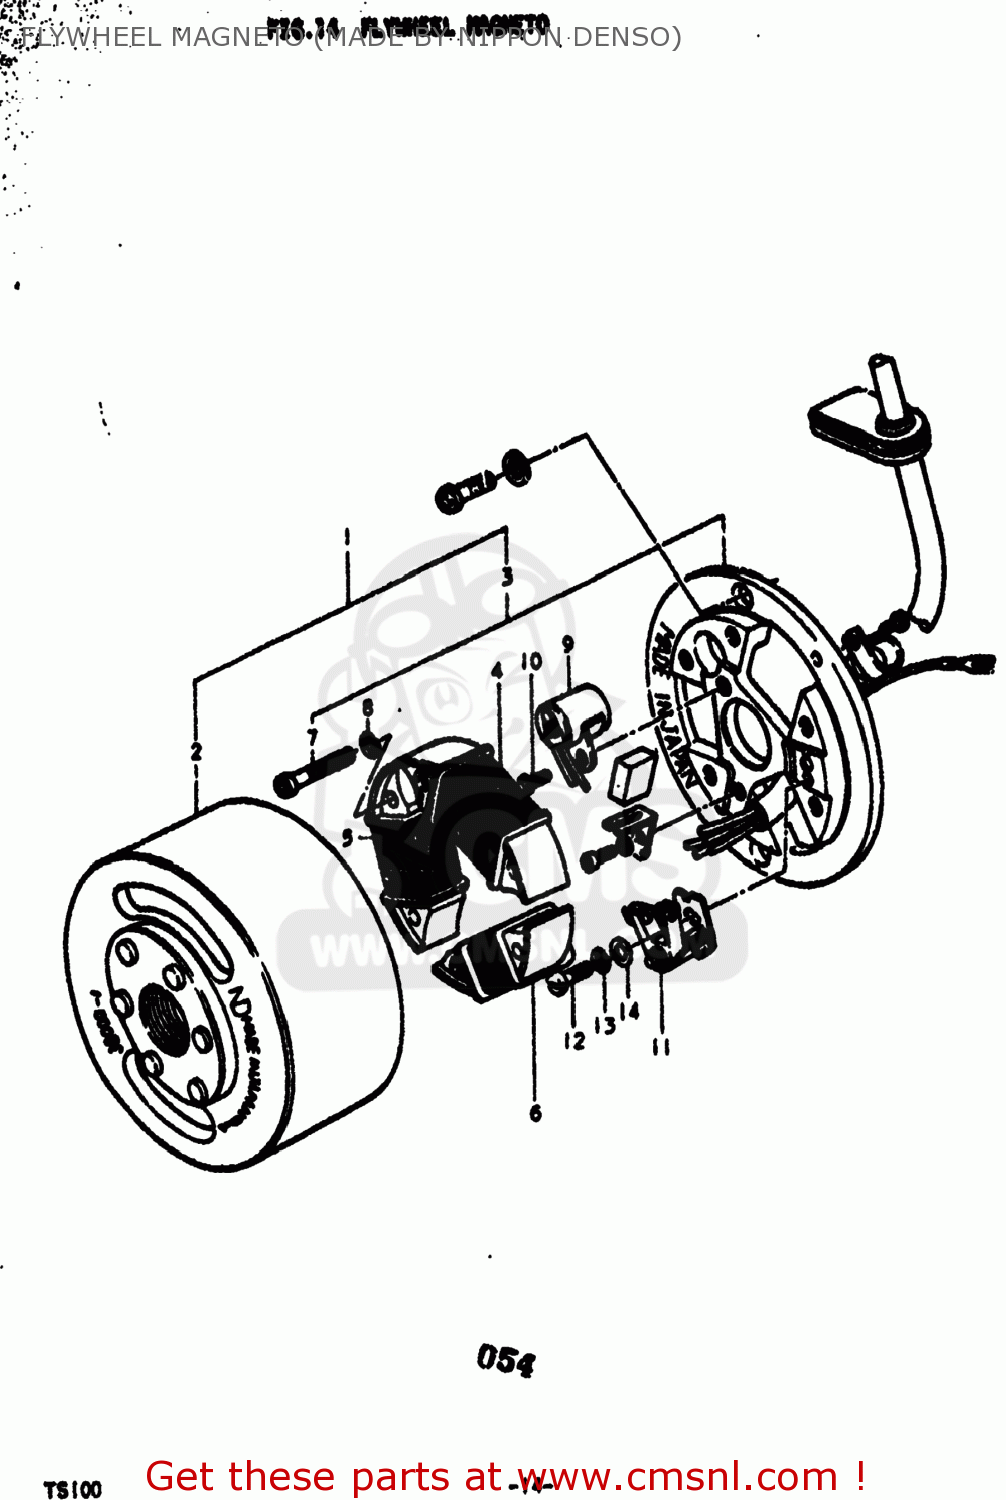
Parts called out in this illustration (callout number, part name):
1	MAGNETO ASSEMBLY
2	ROTOR ASSEMBLY
3	STATOR ASSEMBLY
4	COIL
5	COIL
6	COIL
7	SCREW
8	LOCK WASHER
9	CONDENSER
10	SCREW
11	POINT ASSEMBLY,CONTACT
12	.SCREW
13	LOCK WASHER
14	WASHER
